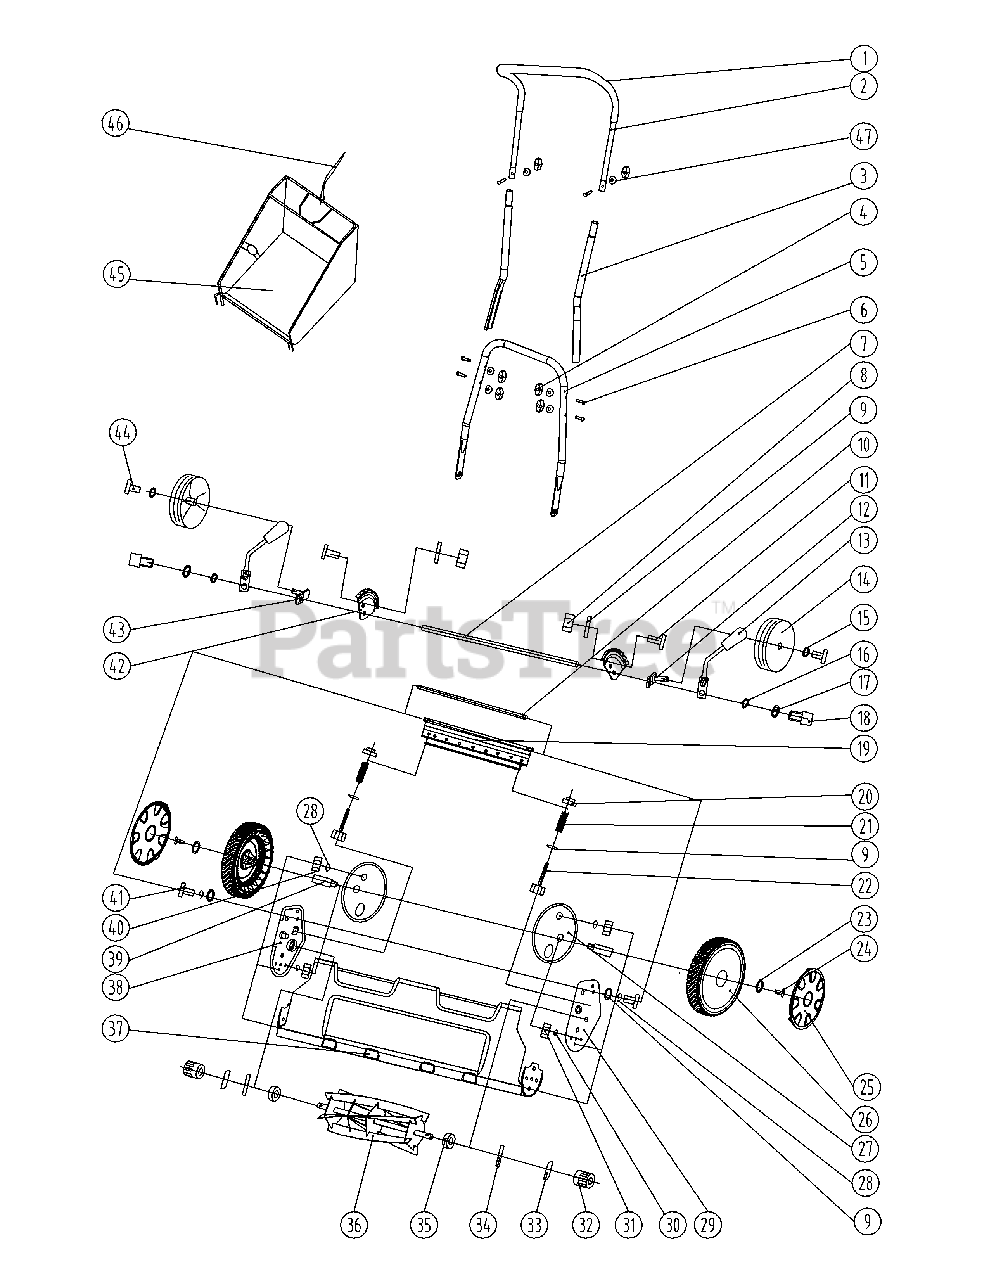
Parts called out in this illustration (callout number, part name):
1	Grip, Handle, 26 x 16 x 630
2	Handle, Upper
3	Handle, Middle
5	Handle, Lower, TB R16
5	Handle, Lower, TB R18
6	Bolt, M6x35gb/T12
7	Shaft, Rear, TB R16, Red
7	Shaft, Rear, TB R18, Red
8	Nut, M8, Gb/T6172.2
9	Washer, 17 x 8.2 x 1.2
10	Pin, TB R16
10	Pin, TB R18
11	Screw, M8-16gbt70.2
12	Bracket, Rear, LH, Red
13	Handle, Adjustment, RH, Red
13	Handle, Adjustment, LH, Red
14	Wheel, Rear
15	Washer, 17 x 8.2 x 1.2
16	Washer, Gb/T955
17	Washer, 20 x 13 x 1
18	Bolt, M8 x 24
19	Bracket, Lower Blade, TB R16, Red
19	Bracket, Lower Blade, TB R18, Red
20	Nut, M8 x 1
21	Spacer, 65mm, 17 x 4 x 48
22	Bolt, M8 x 1 x 65
23	Washer, 25 x 6.5 x 1.5
24	Bolt, M6x20, Gb/T5780
26	Wheel, Complete
27	Bracket, Red
28	Washer, Spacer, Gb/T7244
29	Bracket, Support, LH, Red
30	Washer, 20x10.2x1.4
31	Nut, M10, Gb/T6172.2
32	Gear, 41mm, Pa66
33	Support, 19 x 10 x 5
34	Washer, 34 x 15.5 x 1
35	Bearing, 6002z
36	Blade, Roller, TB R16
36	Blade, Roller, TB R18
37	Shield, Deflector, TB R16
37	Shield, Deflector, TB R18
38	Bracket, Support, RH, Red
39	Axle, Wheel, 19x65.5
40	Nut, M8, Gb/T6170
41	Bolt, M8x16gb/T5781
42	Bracket, Adjustment, 9 Tooth
43	Bracket, Rear, RH, Red
44	Bolt, M6x10 Gb/T5780
45	Grass Bag, TB R18
46	Strap, Grass Bag Hanger, TB R18
47	Saddle Washer
